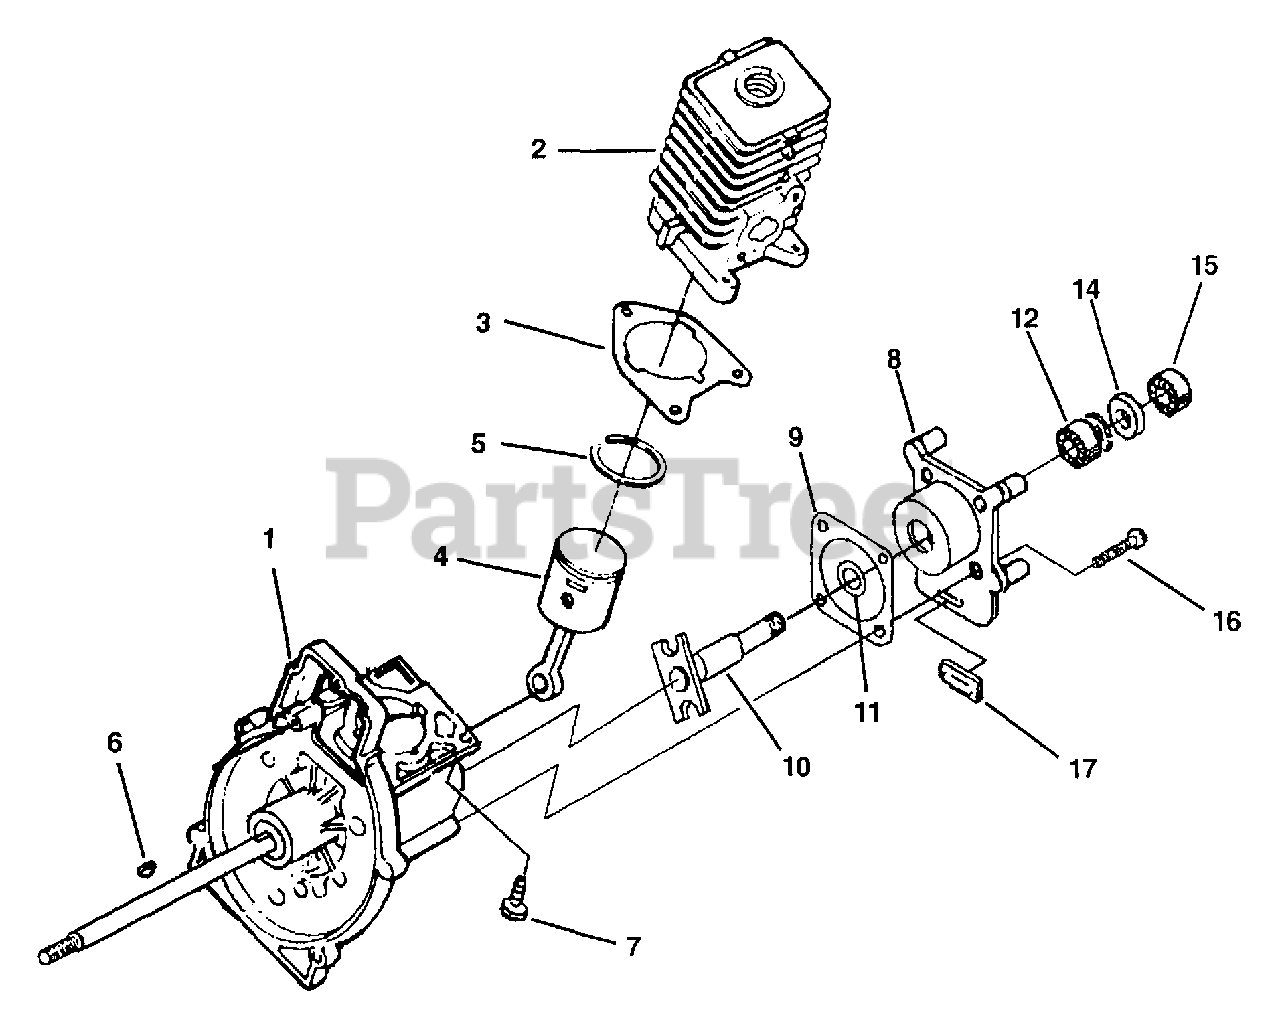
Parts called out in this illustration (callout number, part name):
1	SHORT BLOCK
2	CYLINDER
3	GASKET, CYLINDER
4	PISTON & ROD
5	RING, PISTON
6	KEY, WOODRUFF
7	SCREW, SEMS
8	CRANKCASE COVER
9	GASKET, CRANKCASE
10	SHAFT STARTER
12	BEARING, BALL
13	RING, RETAINING
14	SEAL, SHAFT
15	BEARING, BALL
16	SCREW, MACHINE 10-24 X 3/4"
17	BUMPER, RUBBER
